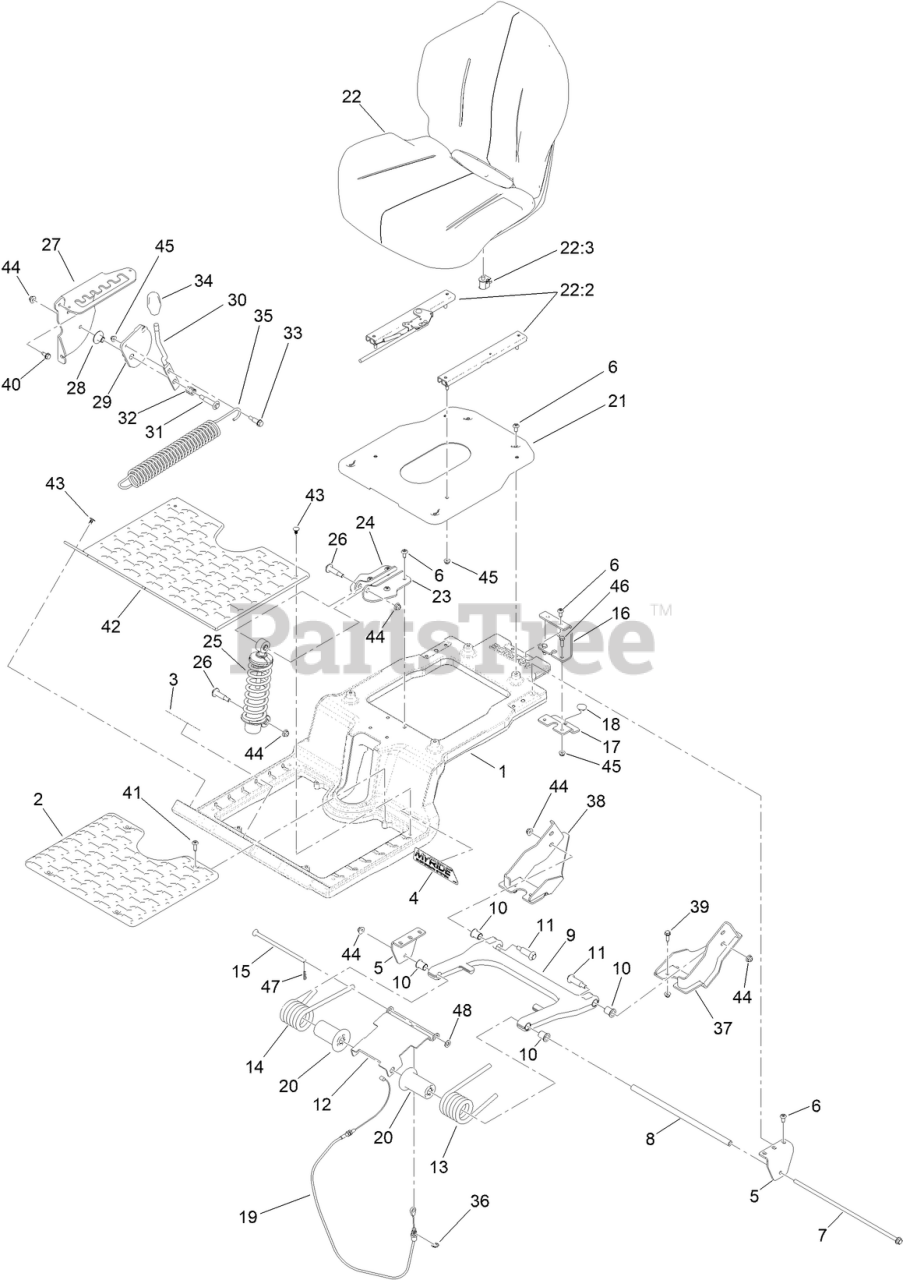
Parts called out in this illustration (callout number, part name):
1	PLATFORM, MYRIDE
2	PLATFORM, MYRIDE
3	DECAL - MYRIDE
4	DECAL - MYRIDE
5	BRACKET-MOUNT, SWING ARM
7	SCREW-HHF
8	TUBE-SPACER
9	ARM-SWING
10	BUSHING-FLANGE
11	BOLT-SHOULDER
12	PLATE-ADJUSTER
13	SPRING-TORSION, LH
14	SPRING-TORSION, RH
15	ROD-ADJUSTMENT
16	BRACKET-CABLE
17	BRACKET LOWER
18	BUMPER-SEAT
19	CABLE-ADJUSTMENT, MYRIDE
20	RETAINER-SPRING
21	PAN-SEAT [BLACK]
22	SEAT ASM - MILSCO CS180D
22:2	KIT-ADJUSTER
22:3	SWITCH-BAIL
23	BRACKET-SHOCK MOUNT, UPPER (LH)
24	BRACKET-SHOCK MOUNT, UPPER (RH)
25	SHOCK/SPRING ASM
26	BOLT-SHOULDER
27	BRACKET-MR GATE
28	BUSHING - FLANGE
29	PULLEY-CAM
30	LEVER-ADJUSTMENT, THREADED
31	BOLT-SHOULDER
32	SPRING-COMPRESSION
33	BOLT-SHOULDER, HHF
34	KNOB-MR
35	SPRING-EXTENSION
36	RING-RETAINING, EXTERNAL
37	MOUNT-MR SWING ARM, LH
38	MOUNT-MR SWING ARM, RH
39	SCREW-THD ROLL, HWH
40	SCREW-HWHTF
41	PIPE-E G R, C2
42	FLOOR MAT
43	PLUG-PLASTIC
44	NUT-HF, NI
45	NUT-HF
46	SCREW-HH
47	PIN-HAIR
48	WASHER-FLAT
